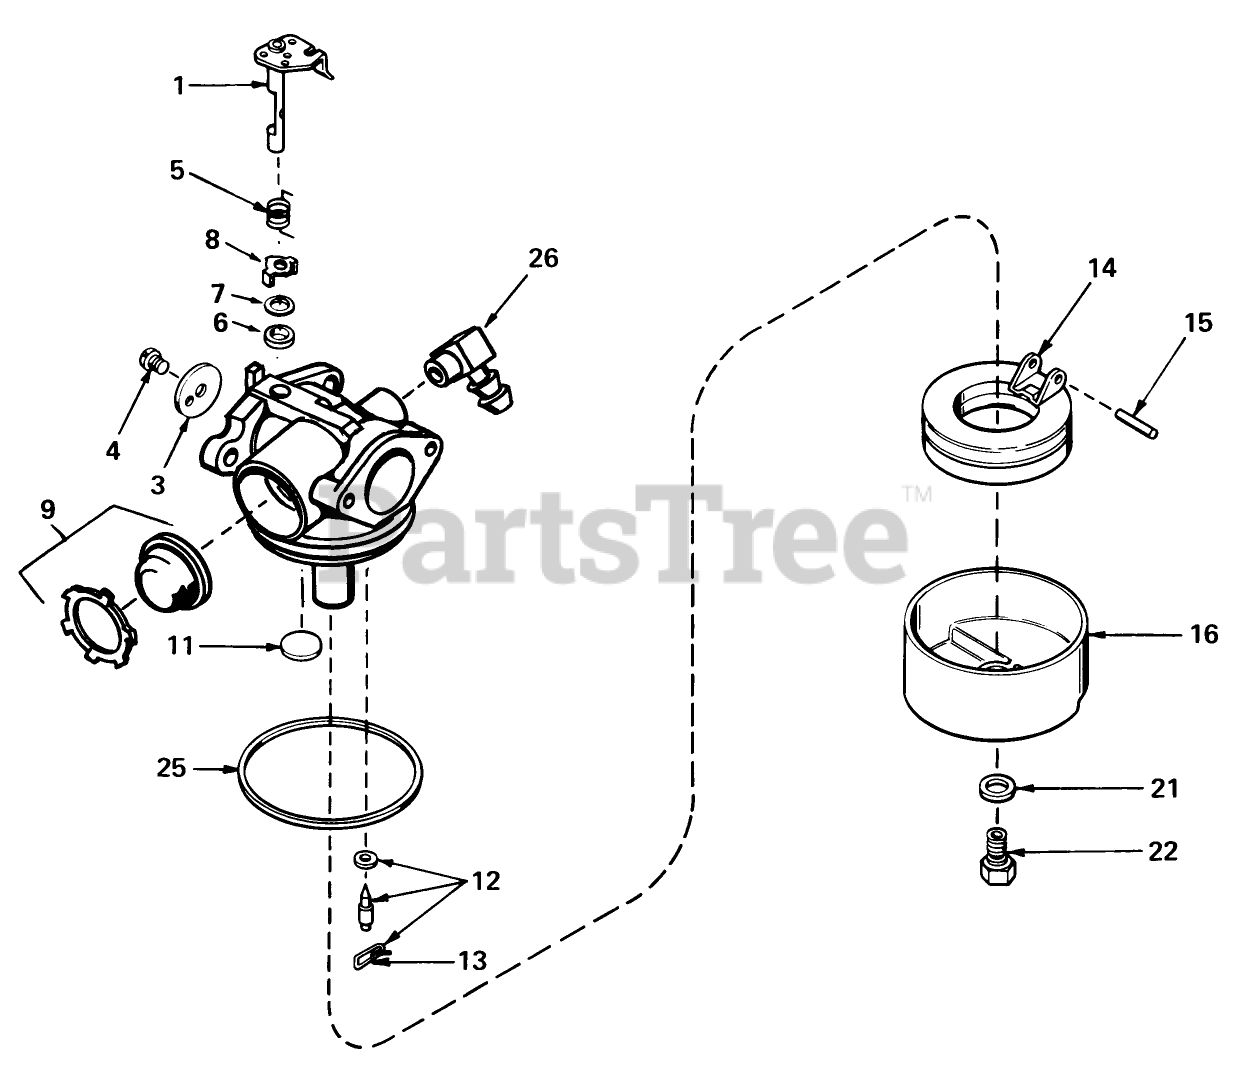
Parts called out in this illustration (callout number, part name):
1	Throttle Shaft and Lever ASM
3	Throttle-Shutter
4	Screw-Shutter
5	Spring, Return
6	Seal-Dust
7	Washer-Seal, Dust
8	Retainer, Seal
9	Primer Assy.
11	Plug-Welch, Atmospheric Vent
12	Inlet Needle, Seat Clip Assy. (Incl. No. 13)
13	Clip-Spring
14	Float
15	Shaft-Float
16	Bowl Float
21	Gasket-Bowl
22	Nut-Float Bowl
25	O Ring-Bowl, Float
26	Fitting-Fuel
